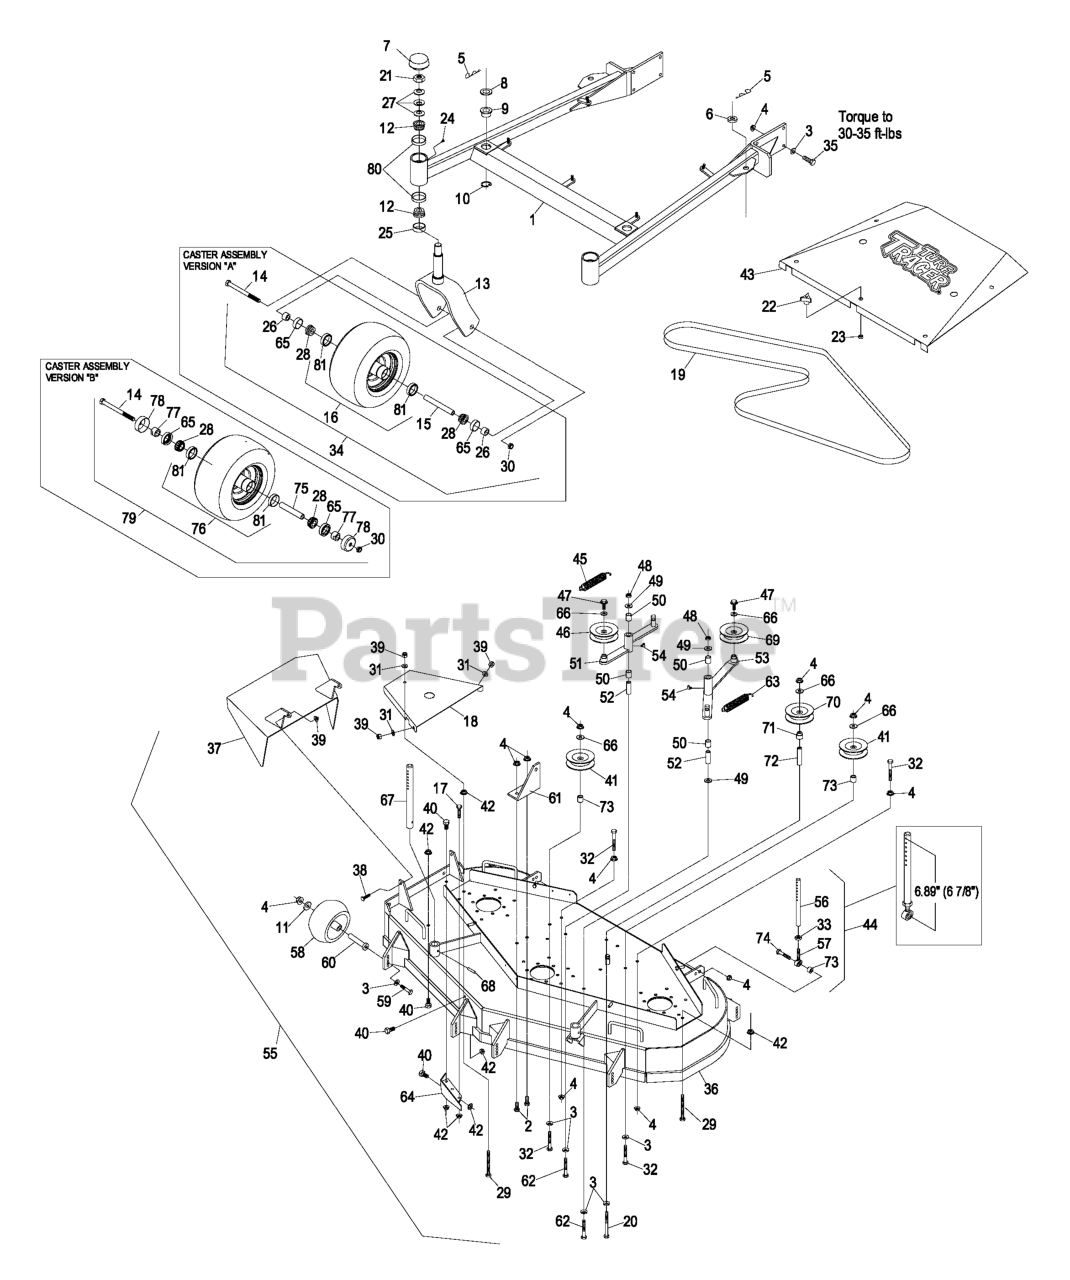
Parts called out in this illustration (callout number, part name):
1	ASM,524 FMD DK SUPPORT,SE
2	SCREW-HH
3	WASHER-BELLEVILLE
4	NUT-HHF, WHIZ
5	PIN,HAIR COTTER
7	CAP-GREASE
8	SPACER-DECK SUPPORT
9	BUSHING-DECK
10	RING-RETAINING
12	Cone-Bearing Tapered Roller
13	WLD, CASTER FORK
14	SCREW-HH
15	SPACER,FRONT CASTER
17	SCREW-HH
18	SHIELD,BELT SIDE FMD524
19	BELT,BLADE DRIVE FMD524
20	SCREW-HH
21	NUT-LOCK, NI
22	KNOB-3 PRONG
25	SEAL-GREASE
26	SPACER-BEARING
27	WASHER-BELLVILLE
28	BEARING-CONE, TAPERED ROLLER
29	BOLT,TAP HH
30	NUT-HEX
31	WASHER-FLAT
32	BOLT-CARR
33	NUT-HEX
35	SCREW-HH
38	SCREW-HH
39	NUT-LOCK, NI
40	SCREW-HH
41	IDLER,PULLEY
45	SPRING-EXTENSION
46	IDLER,PULLEY
47	SCREW-HHF
48	NUT-LOCK, NI
49	WASHER-FLAT
50	SLEEVE-BEARING
51	ASM,IDLER ARM
52	BUSHING-PIVOT, IDLER
53	ASM,IDLER ARM
54	FITTING-GREASE, 90 DEG
55	Complete Deck Assembly
56	LINK,SUPPORT
57	BALLJOINT
58	ROLLER-SCALP, ANTI
59	SCREW-HH
60	BUSHING-ROLLER
61	BRACKET,SPRING ANCHOR
62	SCREW-HH
63	SPRING-EXTENSION
64	WLD,BAFFLE DISCHARGE
65	SEAL-CASTER
66	WASHER-FLAT
67	ROD,DECK SUPPORT
69	PULLEY-IDLER
70	PULLEY-IDLER
71	BUSHING,IDLER
72	SPACER-ANCHOR, CLUTCH
74	SCREW-HH
77	SPACER-NUT
78	GUARD-SEAL
79	WHEEL AND TIRE ASM
80	CUP-BEARING
81	BEARING-CUP
